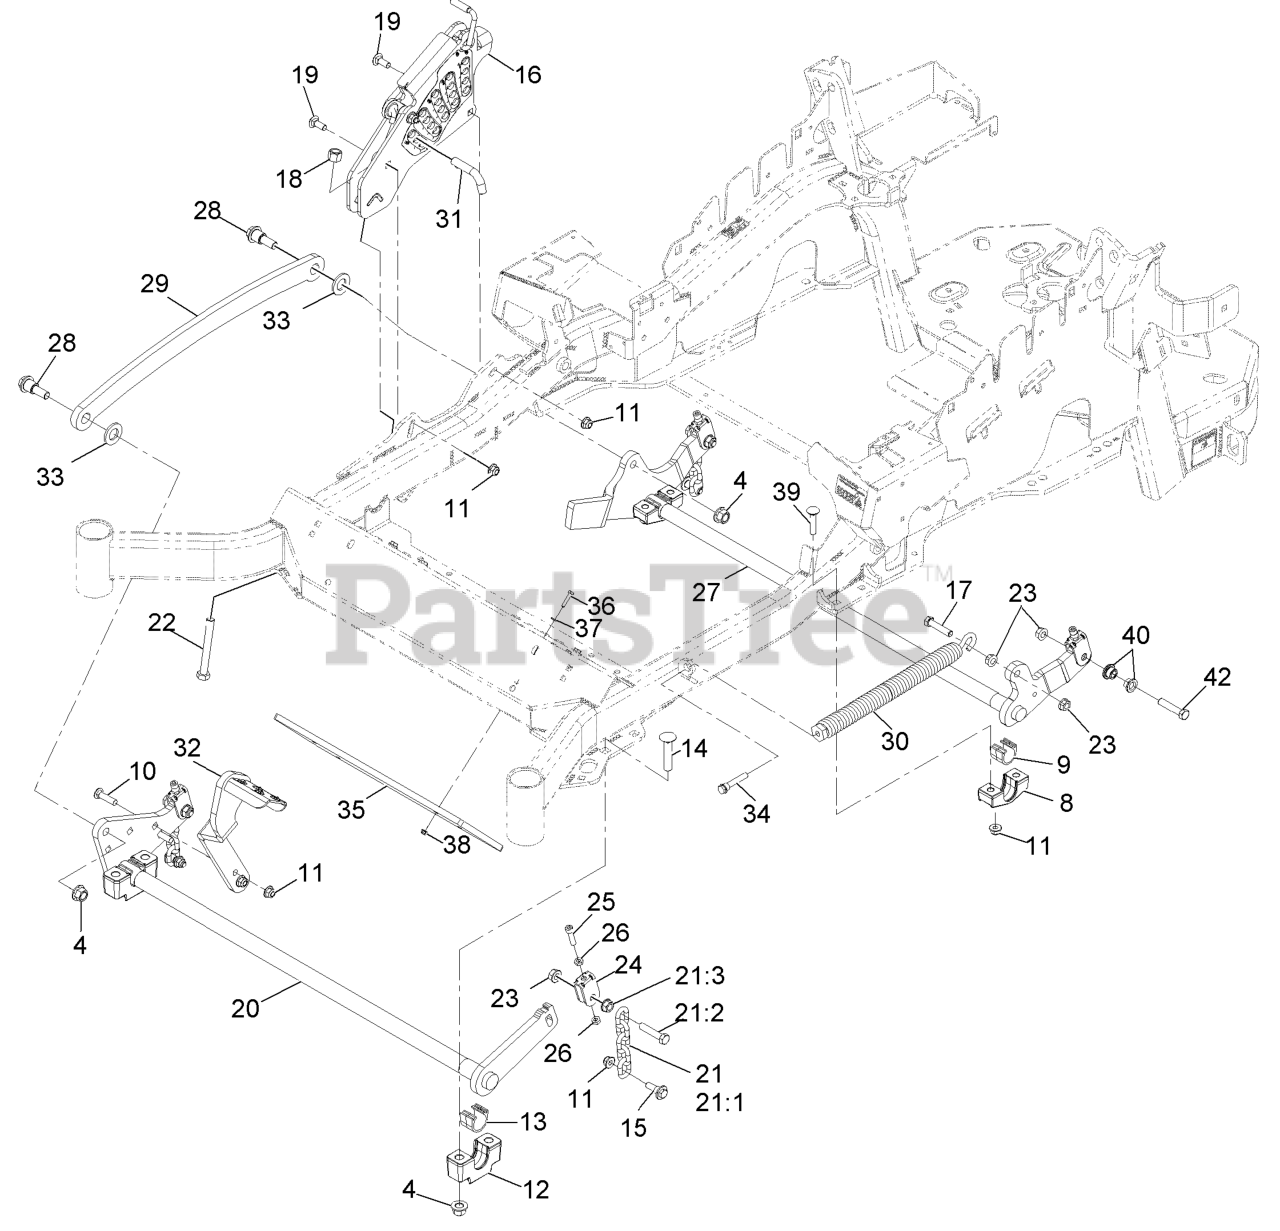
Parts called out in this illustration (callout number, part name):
4	Nut-Lock 1/2-13
9	BEARING-CROSS SHAFT, REAR
10	SCREW-CARR
11	NUT-HF, NI
12	SUPPORT-CROSS SHAFT, BEARING
13	BEARING-CROSS SHAFT, FRON
14	Bolt-Carriage 1/2-13 X 2 1/2 Spl Neck
15	SCREW-SHOULDER, HHF
16	HOC ASM
17	SCREW-HH
18	NUT-LOCK, NI
19	BOLT-CARR
21	DECK LIFT CHAIN ASM
21:1	CHAIN-LIFT, DECK
21:2	SCREW-HH
22	BOLT-TAP
24	YOKE-ADJUST, DECK
25	SCREW-HH
26	NUT-JAM
27	LIFT-DECK, REAR
28	SCREW-SHOULDER, HHF 1/2-13 X 1.12
29	LINK-LIFT, DECK
30	SPRING-EXTENSION
31	PIN-HOC
32	LEVER-FOOT
33	WASHER-FLAT
34	BOLT-SHOULDER
35	WEIGHT,TOE BOARD
36	SCREW-HH
37	WASHER-FLAT
39	SCREW-CARR
40	BUSHING-FLANGED
42	SCREW-HH
